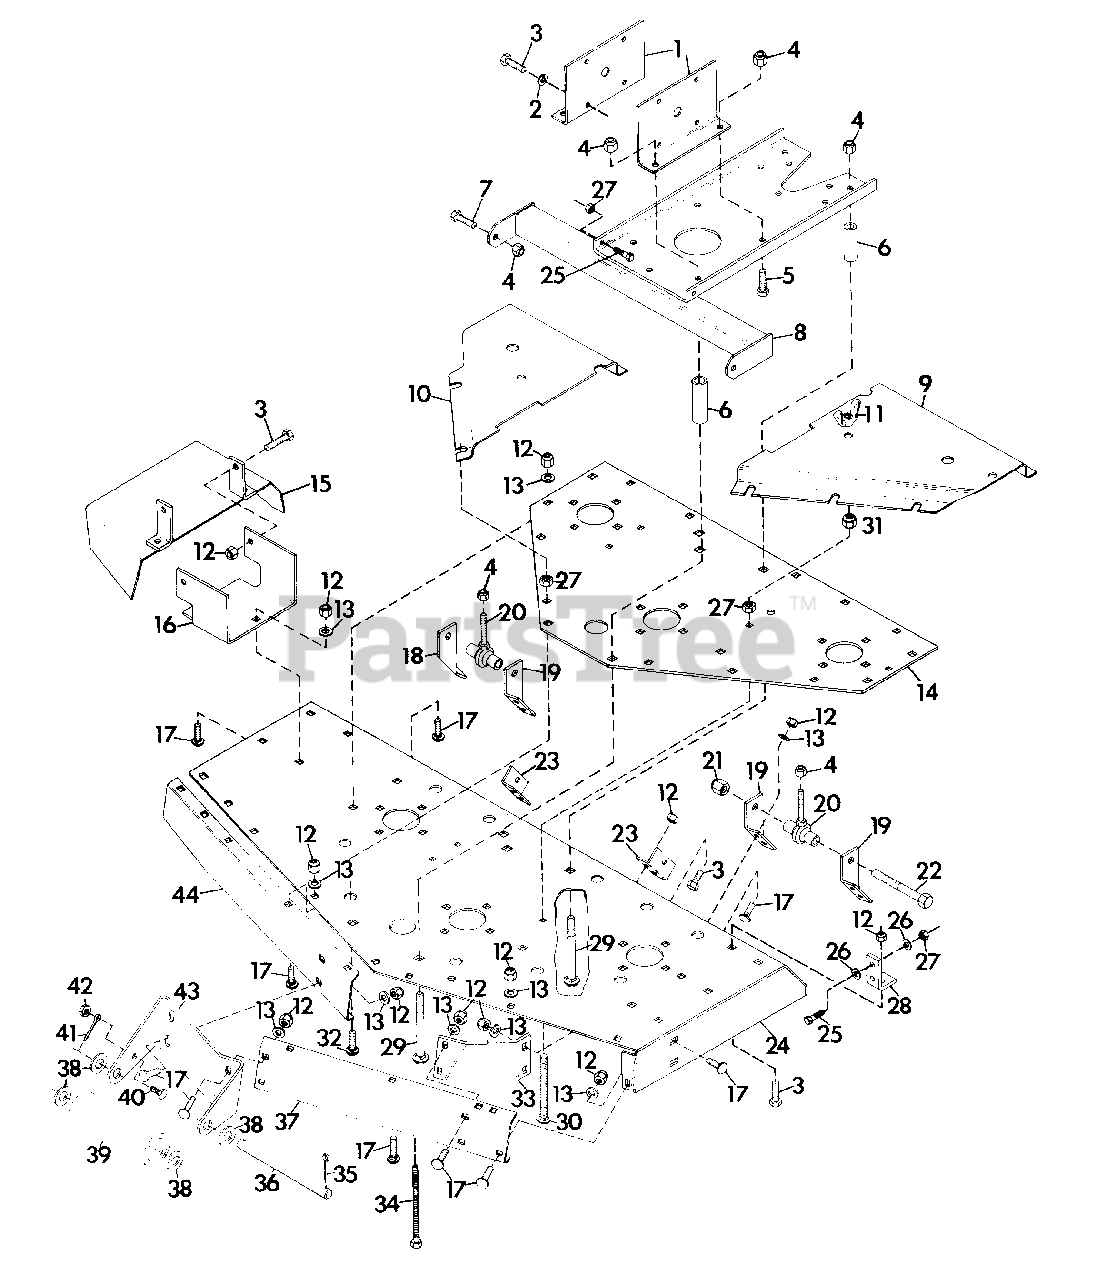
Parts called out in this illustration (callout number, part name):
1	PLATE, GEARBOX SUPPORT
2	WASHER, LOCK 3/8 REG.
3	BOLT, HEX 3/8-16X1.00
4	NUT, LOCK 1/2-13
5	BOLT, HEX 1/2-13X1.25
6	SPACER, .850X.546X2.18
7	BOLT, HEX 1/2-13X2.00
8	WELDMENT, SUPPORT PLATE
9	COVER, BELT L.H.
10	COVER, BELT R.H.
11	NUT, WING 5/16-18
12	NUT, LOCK 3/8-16
13	WASHER, FLAT .406X.812X.065
14	PLATE, DECK SUPPORT
15	WELDMENT, DISCHARGE CHUTE
16	BRACKET, DISCHARGE
17	BOLT, 3/8-16X1.00 RD HD SQ NK
18	PLATE, REAR ADJUSTMENT
19	PLATE, REAR ADJUSTMENT
20	ROD, ENG
21	NUT, LOCK 3/4-10
22	BOLT, HEX 3/4-10X3.50
23	BRACKET, LIFT
24	WELDMENT, 60" OFC
25	BOLT, 5/16-18X1.25
26	WASHER, FLAT .344X.688X.065
27	NUT, JAM 5/16-18
28	BRACKET, LIFT PIVOT
29	BOLT, 1/2-13X3.75 RD HD SQ NK
30	BOLT, 5/16-18X4 RD HD SQ NK
31	NUT, LOCK 5/16-18
32	BOLT, CARRIAGE 5/16-18X1.0
33	BAFFLE, FRONT
34	BOLT, HEX 5/16-18X3.50
35	PIN, COTTER .25X1.0
36	SHAFT, CENTER ROLLER
37	PLATE, FRONT COVER L.H.
38	WASHER, FLAT .656X1.312X.095
39	ROLLER, GAUGE
40	BOLT, HEX 1/4-20X.75
41	PIN, COTTER .25X2.0
42	NUT, HEX 1/4-20
43	BRACKET, ROLLER FRONT
44	PLATE, FRONT COVER
NS	DECAL, DANGER HAND
NS	DECAL, DANGER FOOT
NS	DECAL, WARNING EYE
NS	DECAL, AMERICA
NS	DECALS, PRO MASTER-60 MOWER
NS	STRIPE
NS	DECAL, LUBE
